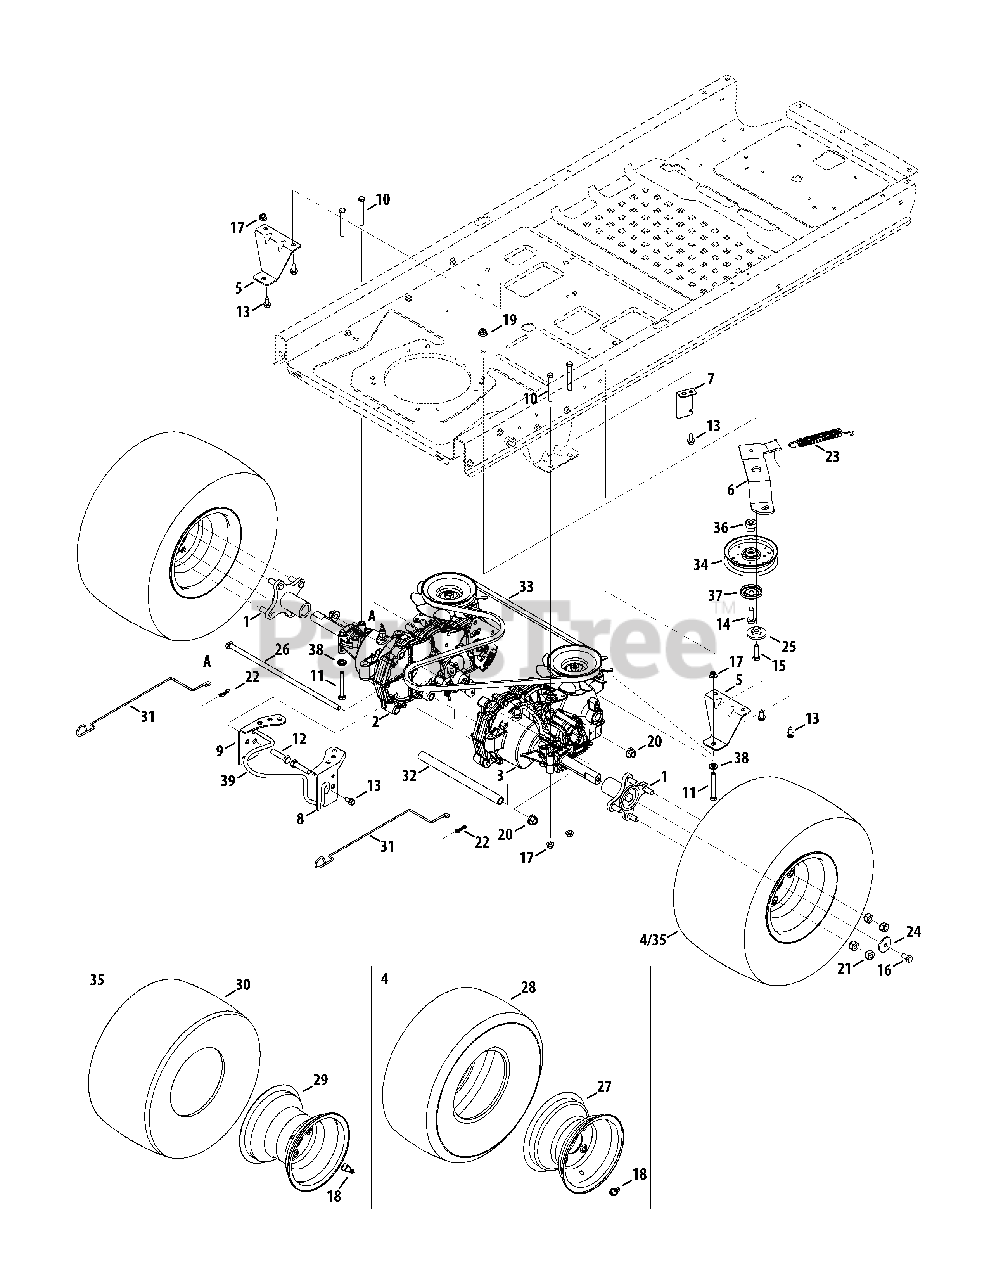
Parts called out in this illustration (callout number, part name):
1	Wheel Hub Assembly
2	Transmission Assembly, LH
3	Transmission Assembly, RH
4	Complete Wheel, 18 x 8.5-8 (42" & 46)
5	Transmission Mounting Bracket
6	Idler Bracket
7	Spring Mounting Bracket
8	Transmission Bracket
9	Transmission Bracket
10	Hex Screw, 5/16-18 x 2.75
11	Hex Screw, 5/16-18 x 2.25
12	Hex Screw, 7/16-20 x 1.75
13	Hex Washer Screw, 5/16-18 x .750
14	Hex Washer Screw, 3/8-16 x 1.250
15	Hex Screw, 3/8-16 x 1.00
16	Hex Screw, 3/8-16 x .75
17	Flange Lock Nut, 5/16-18
18	Valve Tubeless
19	Jam Lock Nut, 3/8-16
20	Flange Lock Nut, 7/16-20
21	Lug Nut, 7/16-14
22	Bow-Tie Cotter Pin
23	Extension Spring, .75 Dia. x 6.02
24	Flat Washer, .390 x 1.50 x .134
25	Shoulder Spacer, .884 x .190
26	Rod, .405 Dia. x 14.0 LG
27	Rim Only, (42" & 26")
28	Tire Only, 18 x 8.5-8 (42" & 46")
29	Rim Only, (50" & 54")
30	Tire Only, 18 x 9.5-8 (50" & 54")
31	Bypass Rod
32	Tube, .51 ID x .75 OD x 10.2
33	Belt, A-Type x 67.0
34	Idler Pulley, 4.25 Dia.
35	Complete Wheel, 18 x 9.5-8 (50" & 54")
36	Shoulder Spacer
37	Pulley Cap
38	Flat Washer, .330 x .630 x .064
39	Engine Keeper Rod (42")
39	Engine Keeper Rod (46", 50" & 54")
